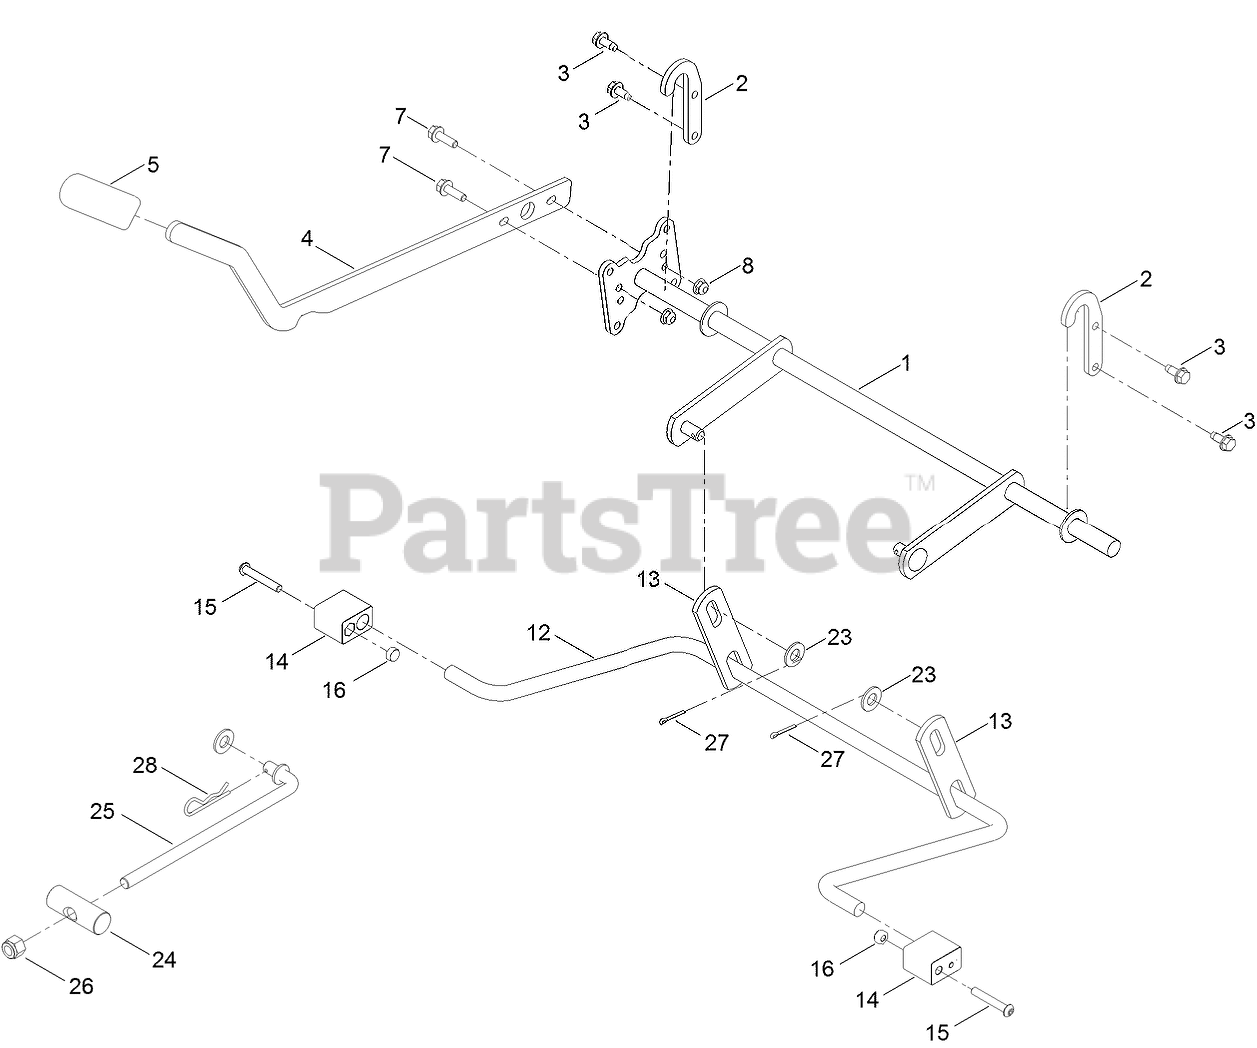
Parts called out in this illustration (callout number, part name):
1	LIFT-DECK, WIDE
2	BRACKET-LIFT
3	SCREW-HWHTF
4	LEVER-LIFT
5	GRIP-LEVER
7	SCREW-HHF
8	NUT-HF
12	ARM-LIFT, REAR (WIDE)
13	LINK-LIFT
14	BLOCK-PIVOT
15	SCREW-HSBH
16	NUT-HEX
23	WASHER-FLAT
24	PIN-PIVOT
25	ROD-MOUNT, DECK
26	NUT-HEX
27	PIN-COTTER
28	PIN-HAIR
